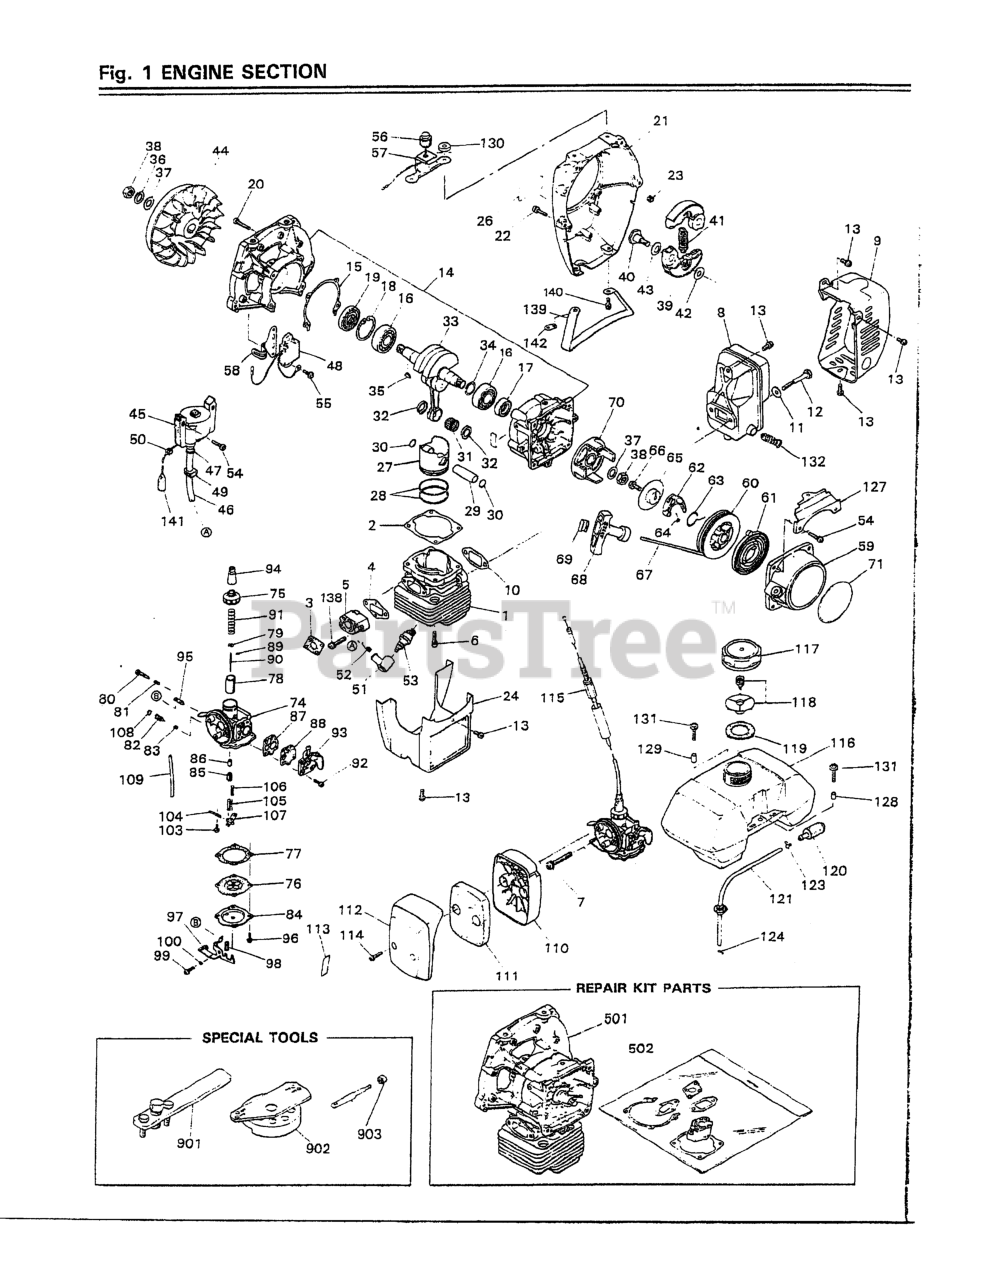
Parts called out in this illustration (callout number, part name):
5	INSULATOR
7	SCREW, M5 X 40
11	WASHER, FLAT (USE 182303)
12	BOLT, M6 x 65
14	CRANKCASE COMPLETE
17	SEAL, OIL - STARTER SIDE
18	RING, SNAP, M35 X 1.5
20	SCREW, M5 x 30(RPLS 0263-00530
22	SCREW, M5 X 20
27	PISTON (NLA)
28	RING, PISTON (RPLS -41210)
29	PIN, PISTON
30	RING, SNAP
31	BEARING
34	SHIM (REPLACES 848-870-G000)
35	KEY
36	WASHER, M10 X 25
37	WASHER, M10 x 1.6
40	SCREW
41	SPRING, CLUTCH
42	WASHER
43	WASHER (USE -51241)
45	COIL ASSEMBLY
46	CORD
47	CAP
51	CAP, PLUG
52	SPRING PLUG (RPLS 3310-71320)
54	SCREW (USE 0263-90520 )
60	REEL (NLA)
61	SPRING, SPIRAL (NLA)
62	RATCHET
63	SPRING (NLA) (REPLACES -75250)
64	SPRING, DOG (NLA)
65	RETAINER (NLA)
67	ROPE
68	KNOB
70	PULLEY (NLA) (RPLS -75210)
74	CARBURETOR (USE 1422-81000)
76	DIAPHRAGM ASSEMBLY (NLA)
77	PACKING
78	VALVE, THROTTLE
79	RECEIVER
81	SPRING, ADJUST
82	SCREW (USE -81271)
83	SPRING, MJ,ADJ
84	COVER, DIAPHRAM
85	HOLDER, NEEDLE
86	JET, NEEDLE
87	PACKING, PUMP
88	DIAPHRAGM
89	CLIP (USE 1030-81000-16)
90	NEEDLE, JET
92	SCREW, M3 x 10
93	COVER, PUMP (RPLS -81800)
96	SCREW, M3 X 8
97	LEVER, TICKLER
98	SPRING, TACKLE
103	SCREW, M3 X 6
105	VALVE NEEDLE
106	SPRING, HINGE
107	HINGE, VALVE
113	LABEL
114	SCREW, M4 X 22
115	CABLE (USE 1650-83100-50)
116	TANK (NO LONGER AVAILABLE)
118	VALVE, VENT
121	PIPE, FUEL (W/O PRIMARY PUMP)
123	CLIP (REPLACES 2841-31280)
131	SCREW, M5 X 22
132	ARRESTER
502	KIT, GASKET (RPLS -06010)
902	SET BLOCK (TOOL)
903	ROD ASSEMBLY (TOOL)
